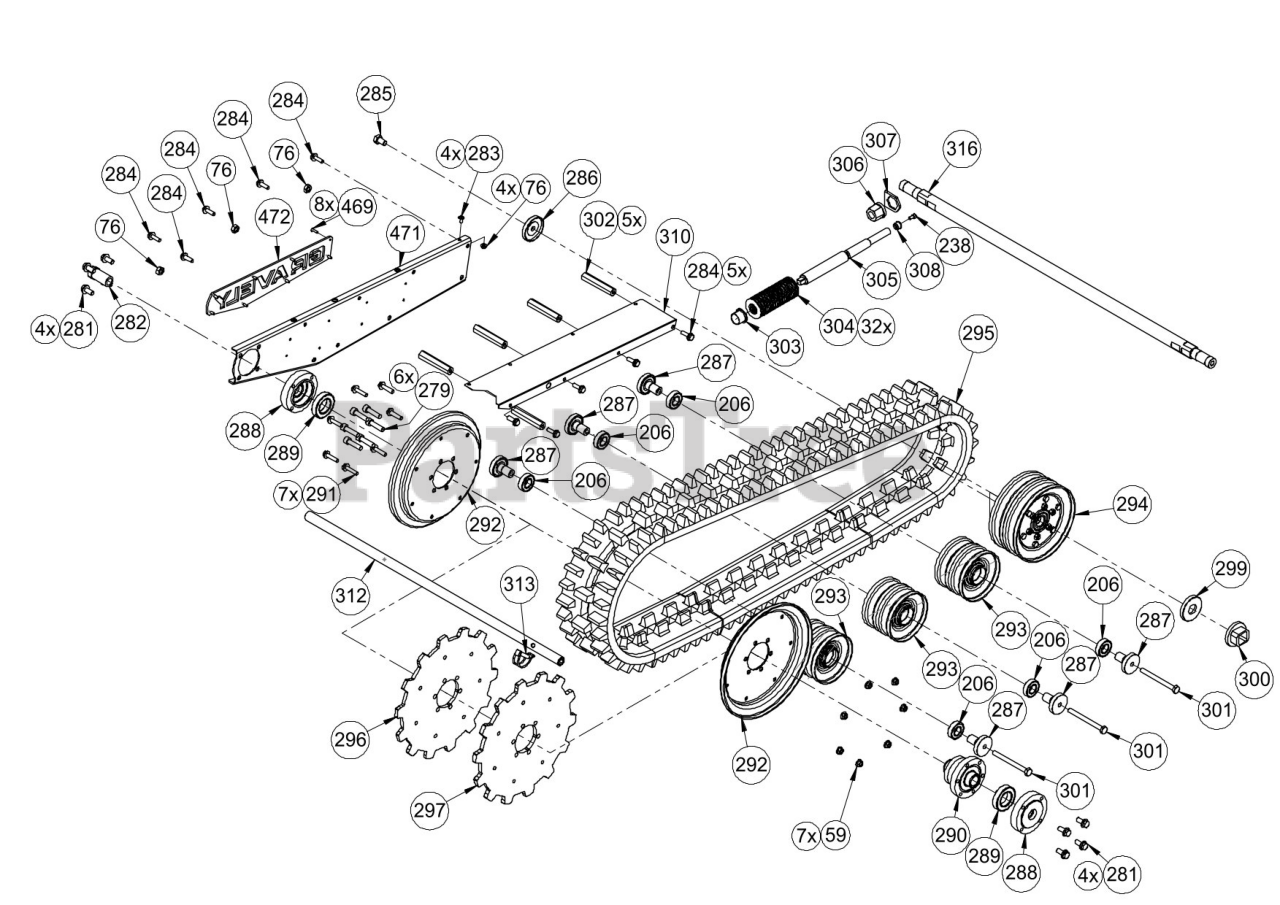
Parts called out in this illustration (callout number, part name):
59	NUT, FLG SLF LK M8 CL 8 ZCC
76	NUT, HEX M10 DIN 934 8 ZCC
206	BRG,BALL .6004-2RSH (20X42X12)
238	SCR, SKH M6X12 DIN ISO 4762 8.8
279	SCR, SKH M10X40 DIN ISO 4762 8.8
281	BLT, SER FLG M10X22 VERBUS RIPP ZIL.
282	NUT, AXLE
283	TORX FBHCS M6X12 8.8
284	BLT, SER FLG M8X25 VERBUS RIPP 100
285	BLT, HEX M12X20 DIN 933 8.8 ZCC
286	COVER, BEARING (OUTSIDE)
287	BUSHING, SLEEVE
288	SHIELD, BEARING
289	BRG,BALL .6007-2RS DIN625(35X62X14)
290	HUB, SPROCKET
291	BLT, SER FLG M8X35 VERBUS RIPP BK
292	HALF, SPROCKET PULLEY
293	ROLLER, TRACK
294	ASSY, IDLER WHEEL
295	TRACK, RUBBER
296	HALF, SPROCKET (8)
297	HALF, SPROCKET (10)
299	COVER, BEARING (INSIDE)
300	BUSHING, AXLE
301	BLT, HEX M10X11 DIN 931 8.8 ZCC
302	NUT, COUPLING
303	BSHG, DU FLG BB2521DU
304	WSHR, BLVL A50X25.4X3 DIN 2093
305	SHAFT, TENSION
306	NUT, FLG M20 DIN 6331 ZCC
307	INDEXER, THRUST BUSHING
308	BUSHING, THRUST
310	COVER, ROLLER GUIDE (LH)
312	SHAFT, EXTENSION
313	PIN, LYNCH
316	AXLE, IDLER WHEEL
469	RVT, 4.8X16.9 ST ZCC
471	SHIELD, ROLLER GUIDE (LH)
472	SIGN, GRAVELY (LH)
